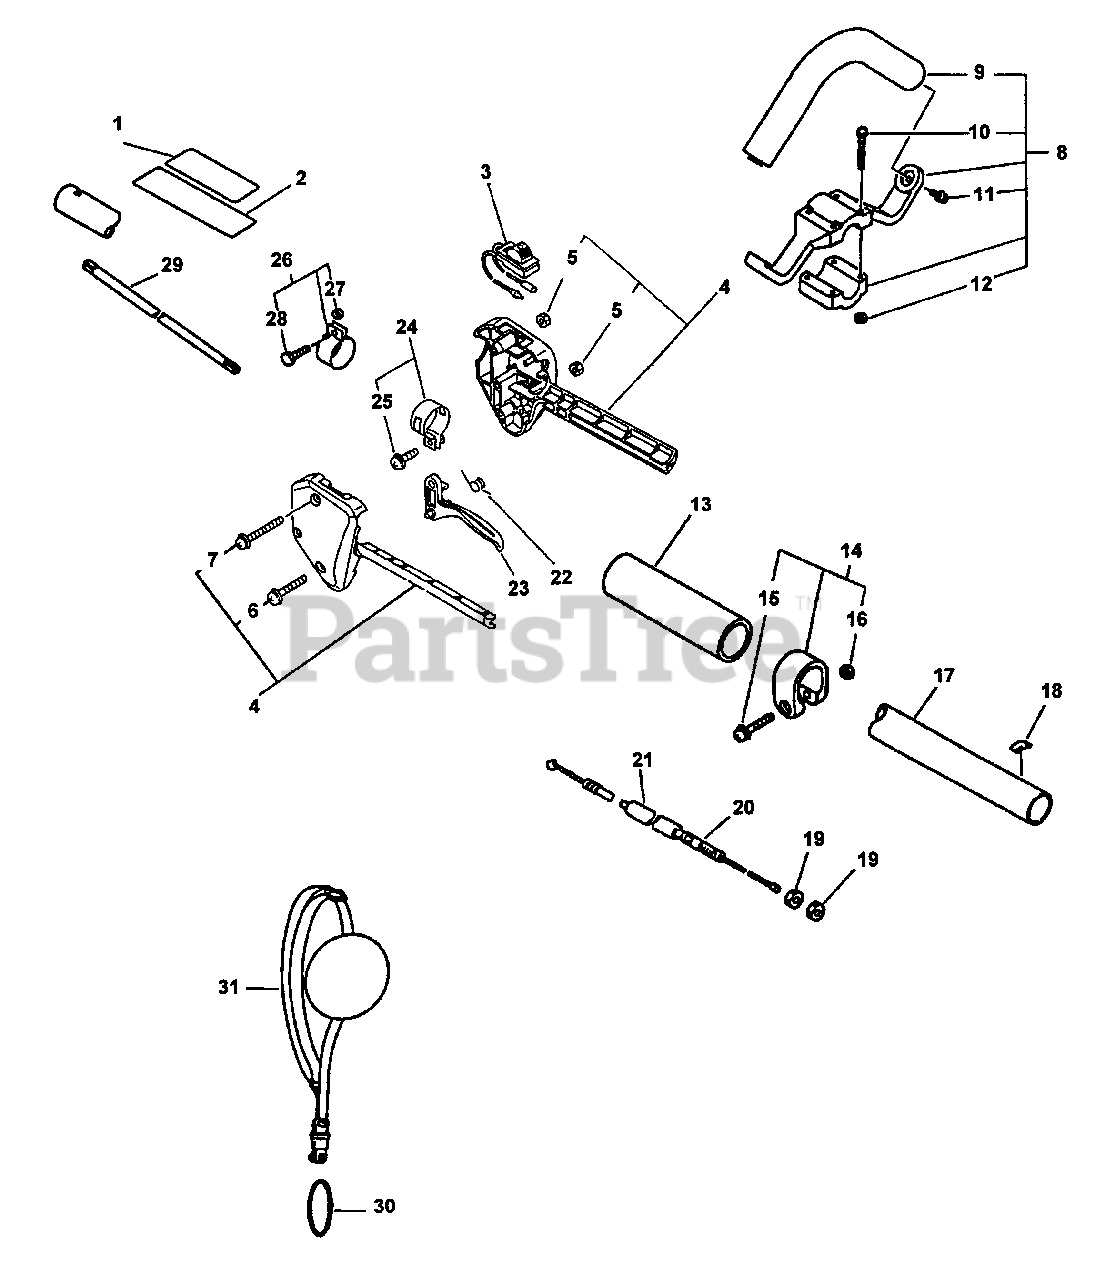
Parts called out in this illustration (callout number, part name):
1	LABEL - CAUTION
2	LABEL - CAUTION
3	IGNITION SWITCH ASSY
4	CONTROL HANDLE KIT
6	SCREW - 5X25
7	SCREW - 5X35
8	LOOP HANDLE ASSY
9	HANDLE - FRONT
10	SCREW - 5X35
11	SCREW - 5X14
13	GRIP, HANDLE
14	CLAMP KIT
15	SCREW - 5X28
17	PIPE, MAIN
18	LABEL - ALIGNMENT
20	CABLE, THROTTLE
21	TUBE - VINYL
22	SPRING, TRIGGER
23	TRIGGER, THROTTLE
24	CLAMP KIT
25	SCREW - 5X12
26	CLAMP
28	BOLT - 5X18
29	DRIVESHAFT
31	SHOULDER STRAP ASSY
